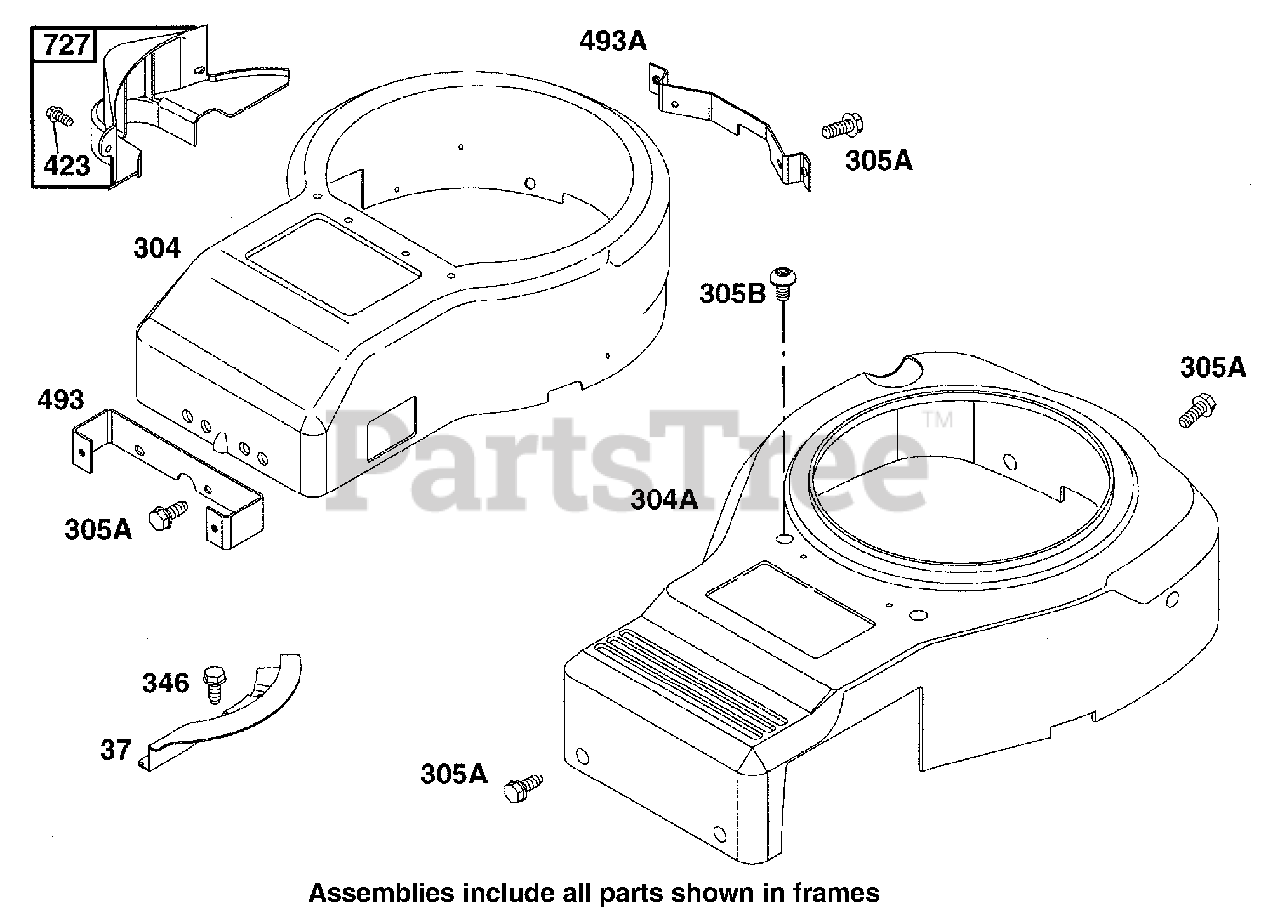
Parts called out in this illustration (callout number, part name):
37	Flywheel Guard
304	Blower Housing
304A	Blower Housing Cover
305A	Hex Screw
305B	Torx Screw
346	Hex Screw
423	Shoulder Screw
493	Mounting Bracket (Front)
493A	Mounting Bracket (Rear)
727	Starter Drive Cover
